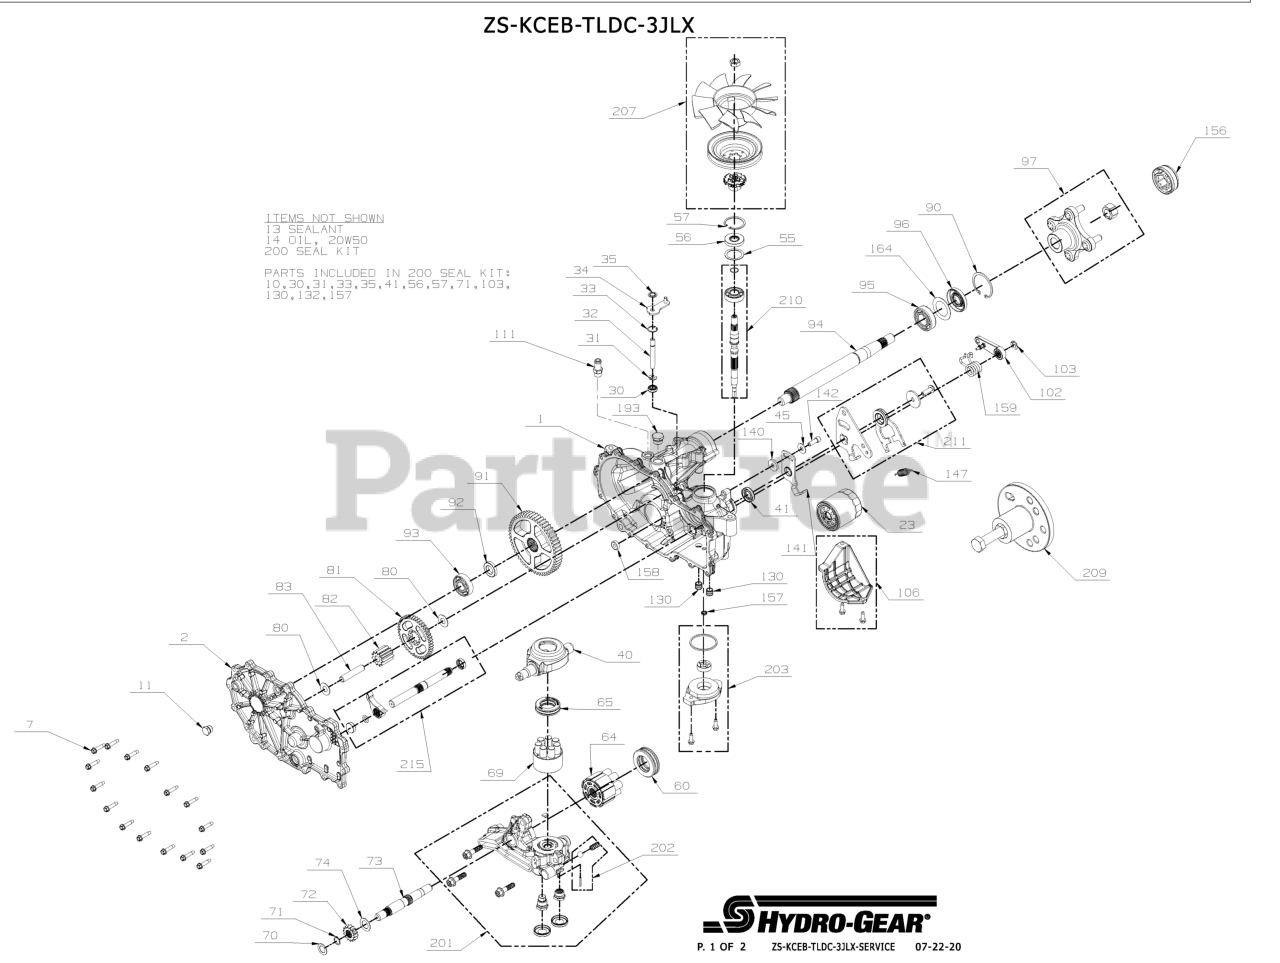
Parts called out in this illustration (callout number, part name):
1	KIT, MAIN HOUSING LH, CHARGE, CONTROL
2	KIT, COVER, SIDE LH
7	SCREW,HEX WASHER 1/4-20X1.125
11	PLUG EXT HEX VENT 9/16 18
13	SEALANT TUBE 10.1OZ.
14	FLUID, HYDRO 20W50 QT
14	FLUID, HYDRO 15W50 QT
23	FILTER, HYDRO-GEAR 2800 TRANS
30	Seal, lip .375 x 375 x 325
31	RING. RETAINING
32	ROD, BYPASS
33	RING, RET .750
34	HG BYPASS ARM (52370)
35	RING, RTNG .
40	TRUNNION, SWASHPLATE
41	SEAL, LIP 18X32X7
55	WASHER 1.23X1.56X.04
56	SEAL, LIP 17X40X7
57	RING, RET 1.56 INT
60	HG THRUST BEARING (51462)
64	HG 16CC CYLINDER BLOCK (71579)
65	HG THRUST BLOCK (53502)
69	HG SEVEN PISTON BLOCK (71971)
70	WASHER .63X1.0X.05
71	RING, RET 62 EXT
72	GEAR 14T STEEL
73	SHAFT, MOTOR
74	WASHER .71 X 1.16 X .04
80	WASHER .5X1.0X.032
81	GEAR 45 TOOTH
82	GEAR 11 TOOTH STEEL
83	JACK SHAFT (PIN)
90	RING, RETAINING
91	GEAR, 54T
92	SPACER
93	KIT, BEARING
94	GEAR, 54T
95	BEARING, BALL 25.4 X 52 X 15
96	SEAL, LIP
97	KIT, HUB 4 BOLT
102	KIT, BRAKE ARM LEFT HAND
103	CLIP,BRAKE ARM HYDROGEAR 52027
106	KIT, FILTER GUARD
111	KIT, FITTING 1/2 BEADED 9/16
130	TUBE CHARGE TRIPLE ORING
141	ARM, NEUTRAL LEFT
142	SHCS 5/16-24X1 PATCH
147	SPRING, EXTENSION
156	CAP, AXLE
157	KIT GEROTOR SEAL
158	MAGNET, RING
159	SPRING, TORSION, CW
164	WASHER, 1.355 x 2.035 x .021 FLAT
200	HG SEAL KIT (71976)
201	KIT, CENTER SECTION, LH CHARGE
202	KIT CHARGE RELIEF
203	KIT, CHARGE PUMP
207	KIT, FAN/PULLEY
209	HUB PULLER 5 BLT
210	INPUT SHAFT HG 71978
211	RING, RTNG .
215	KIT, OUTBOARD, RH ROT B / LH ROT A
